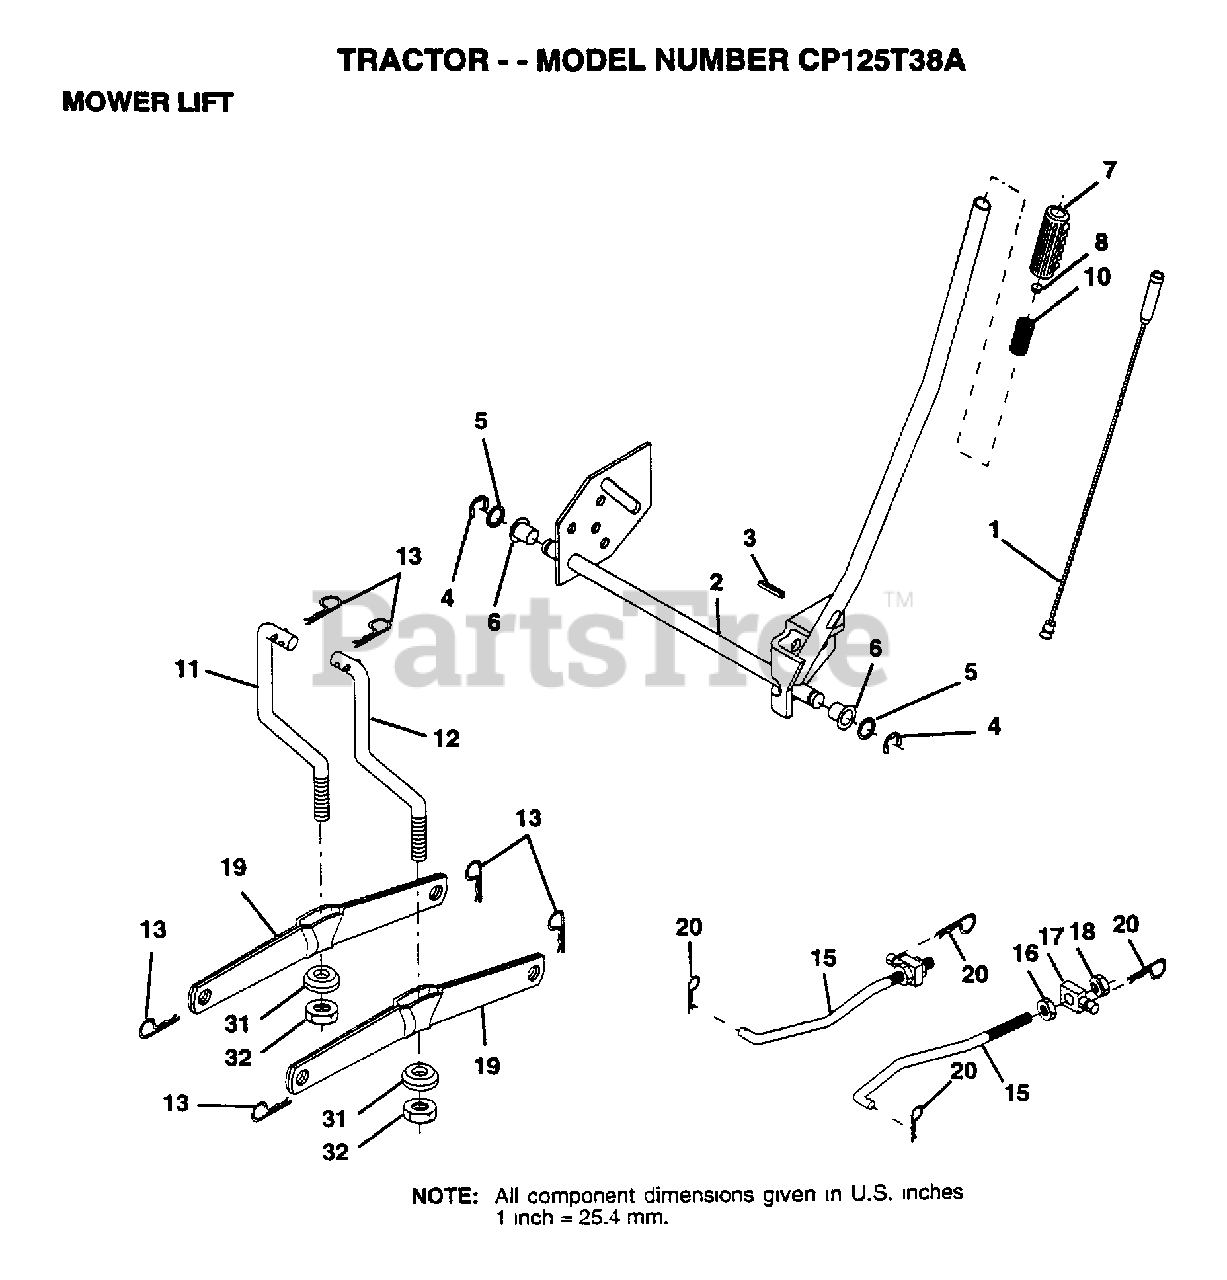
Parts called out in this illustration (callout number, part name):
1	WIRE ASM
3	PIN-GROOVE LT
5	WASHER
6	NYLON BEARING
7	GRIP
15	LINK.FRONT
16	NUT
17	TRUNION
18	NUT.LK.W/WSH.1/2.
19	ARM SUSP REAR
20	RETAINER.SPRING
31	BEARING PVT LH
32	NUT.CROWNLOCK.3/8
